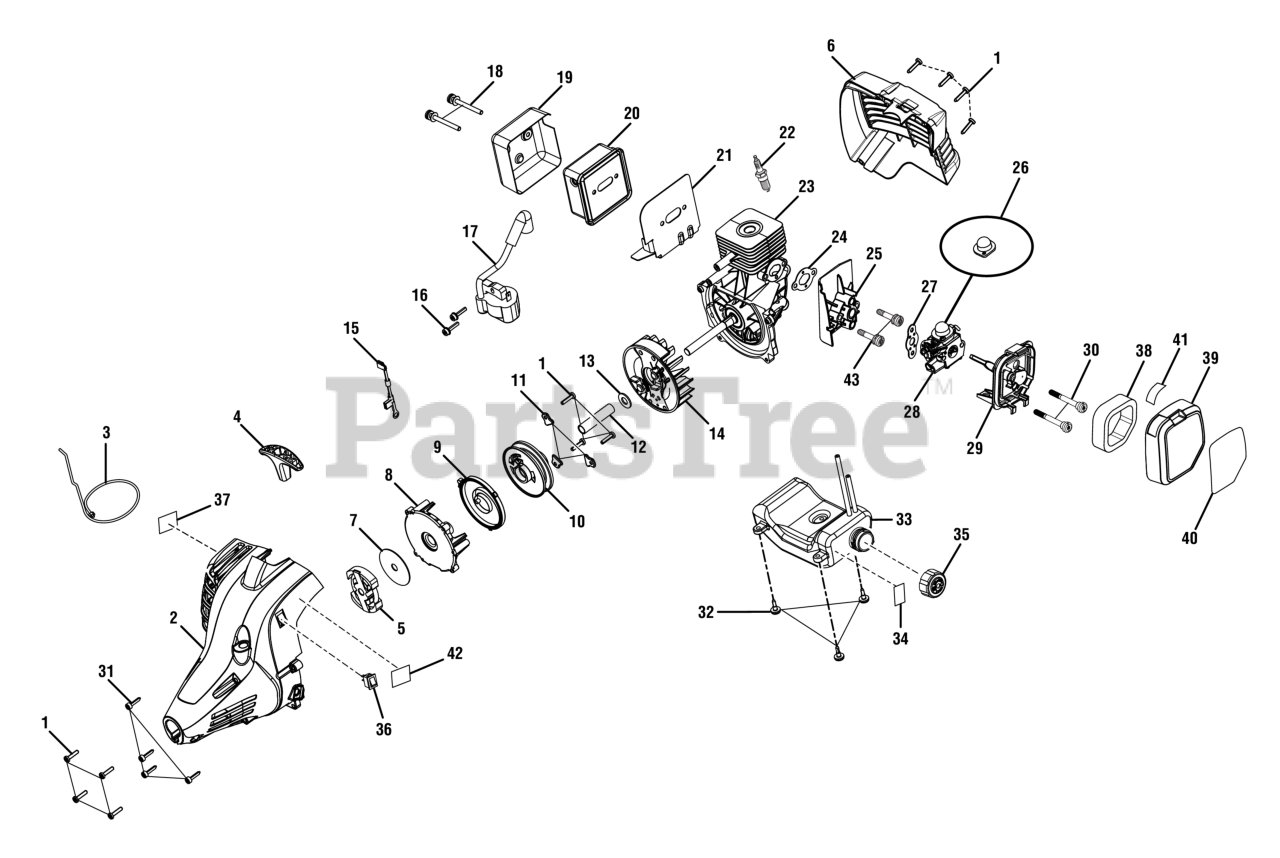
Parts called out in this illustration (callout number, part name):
1	Screw (M4 x 20 mm, T20 Torx Pan Hd. S.T.)
2	Front Housing Assembly (Inc. Key No. 37 & 42)
3	Starter Rope (42 in.)
4	Starter Grip
5	CLUTCH ASSEMBLY
6	Rear Housing
7	Washer (ID9.63 x OD50.75 x 1.10t)
8	Starter Housing
9	Spring & Container Assembly
10	Starter Pulley Assembly
11	Pulley Retainer
12	Spacer Tube
13	Washer (ID9.75 x OD20 x 1.6t)
14	Flywheel Assembly
15	Lead Assembly
16	Screw w/Washer (M4 x 19 mm, T20 Torx Pan Hd. S.T.)
17	Ignition Module
18	Screw w/Washers (10-24 x 2-1/8 in., T25 Torx Truss Hd.)
19	Muffler Housing
20	Muffler Assembly
21	Muffler Gasket
22	SPARK PLUG CHAMPION - RCJ-6Y
23	Short Block Assembly
24	Inner Heat Dam Gasket
25	Heat Dam Deflector
28	Carburetor Assembly
29	Airbox Base Assembly
30	Screw (M5 x 45 mm, T20 Torx Truss Hd.)
31	Screw w/Washer (M4 x 16 mm, T25 Torx Truss Hd.)
32	Shoulder Screw w/Washer (M4 x 14 mm, T25 Torx Truss Hd.)
33	Fuel Tank w/Label & Cap Assembly
34	Fuel Tank Warning Label
35	Fuel Cap Assembly
36	Stop Switch (Momentary Contact)
37	Warning Label (Combustion)
38	Air Filter (Element)
39	Air Box Cover (Inc. Key No. 40-41)
40	Starting Label
41	Choke Label
42	Primer Bulb Location Label
43	Screw w/Washers (M5 x 30 mm, T25 Torx Pan Hd.)
